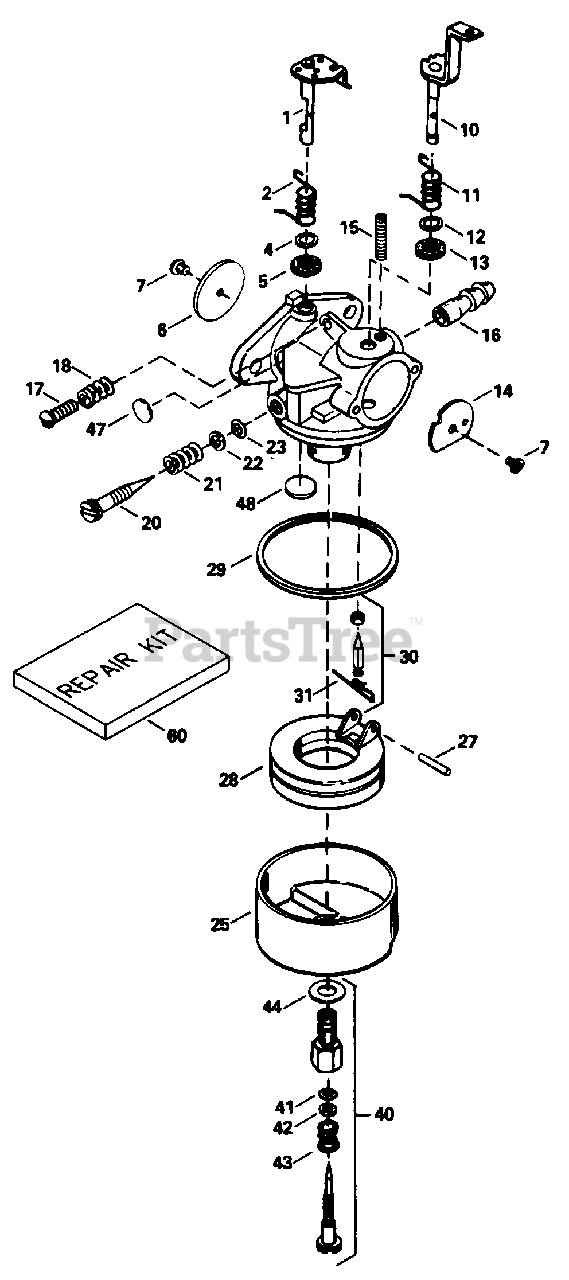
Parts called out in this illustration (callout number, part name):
1	Throttle Shaft & Lever Ass'y.
2	Throttle Return Spring
4	Dust Seal Washer
5	Dust Seal
6	Throttle Shutter
7	Throttle & Choke Shutter Screw
10	Choke Shaft & Lever Ass'y.
11	Choke Return Spring
12	Dust Seal Washer
14	Choke Shutter
15	Choke Positioning Spring
16	Fuel Fitting
17	Idle Speed Screw
18	Tension Spring
20	Idle Mixture Screw
21	Idle Tension Spring
22	Washer, Idle Screw
25	Float Bowl
27	Shaft, Float
28	Float
29	O-Ring, Float Bowl to Body
30	Inlet Needle, Seat & Spring Clip
31	Spring Clip
40	Adjustment Screw Ass'y., Main
41	O-Ring, High Speed Mixture Screw
42	Washer, High Speed Mixture Screw
43	Tension Spring, High Speed Mixture Screw
44	Bowl Nut Washer
47	Welch Plug, Idle Mixture Well
48	Welch Plug, Atmospheric Vent
60	Repair Kit
